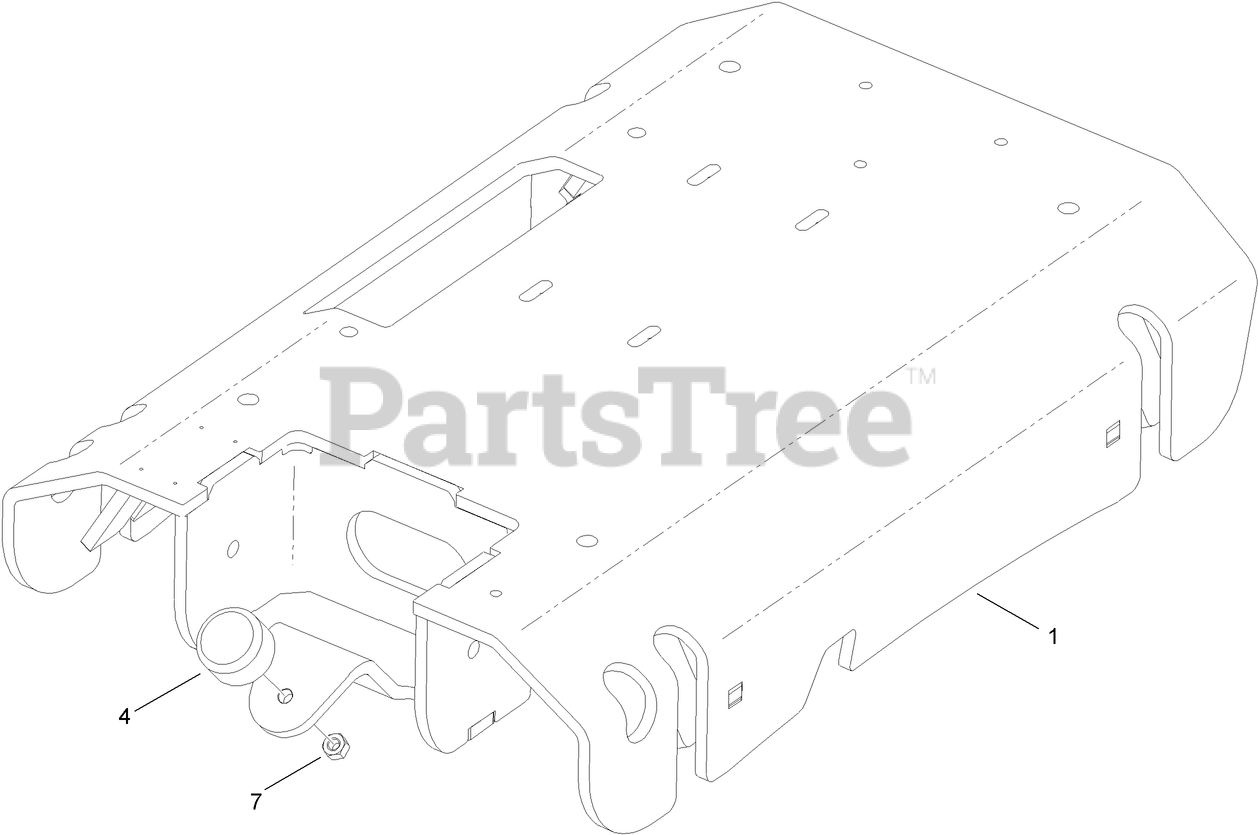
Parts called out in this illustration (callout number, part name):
1	PLATE-ENGINE
4	BUMPER-RUBBER
7	NUT-LOCK, NI
